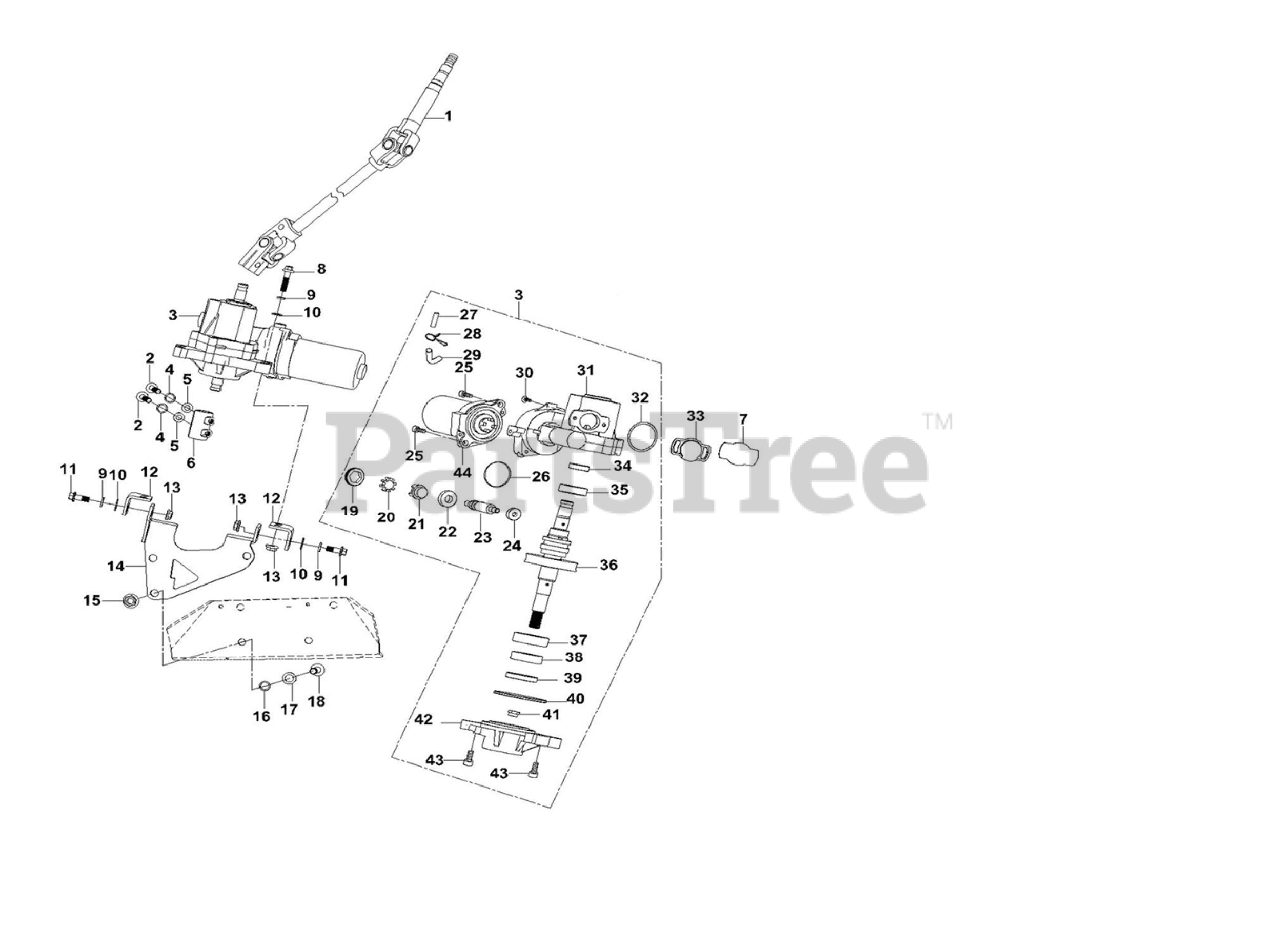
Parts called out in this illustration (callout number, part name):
1	SHAFT - STEERING WHEEL
2	Flange Bolt M6x25
3	Electrical Power steering Comp
4	WASHER - SPRING LOCK 8
5	WASHER - FLAT
6	EPS CONNECTOR BRACKET
7	COVER - EPS SENSOR
8	Hexagon flange bolts M8x35
10	Spring Washer-8
11	Hexagon Flange Bolt M8x20
12	BRACKET
13	NUT M8x35
14	BRACKET EPS PLATED II
15	LOCK NUT M10x1.25
16	Spring Washer10
18	Hexagon Flange BoltM10x1.25x45
19	Nut hexagon socket M30x1
20	Bumper EPS
21	Join EPS shaft
22	Bearing 16001
23	Worm shaft
24	Bearing 608-Z
25	Bolt hexagon socket head M8x25
26	Seal motor 58x2.4
27	Hose breather
28	Clip
29	Pipe breather
30	Screw cross flange head M5x16
31	Case motor
32	Seal sensor 28x2
33	SENSOR - EPS
34	Seal 20x30x8
35	Bearing 6004
36	Shaft worm gear
37	Bearing 6205
38	Bearing 16005
39	Seal 27x47x7
40	O-ring 72x2
41	Nut lock
42	Cover motor
43	Bolt hexagon socket head M6x40
44	Motor EPS
